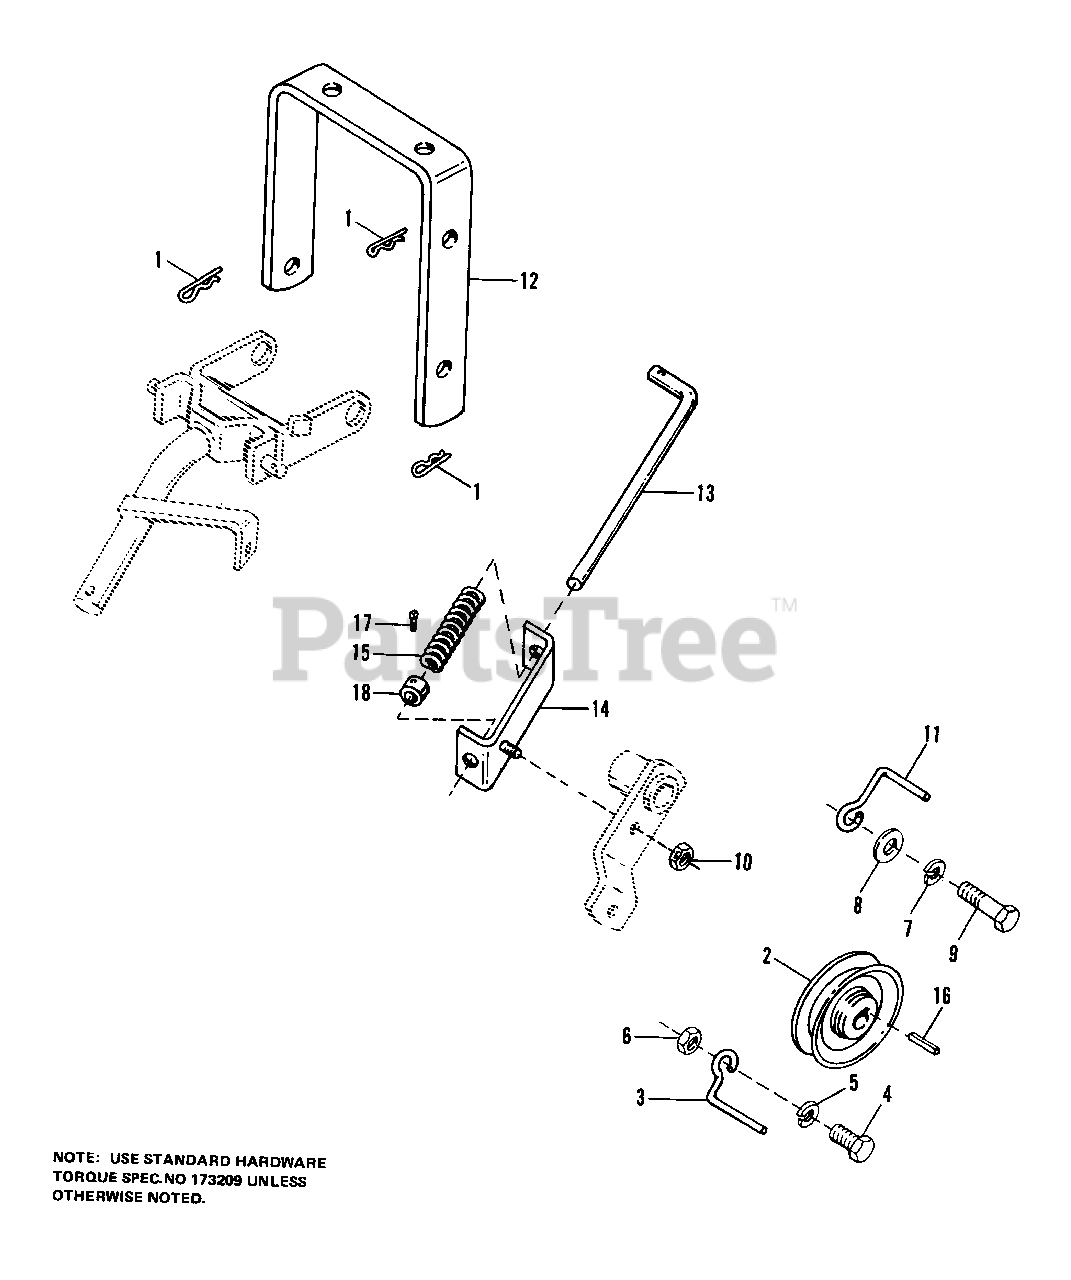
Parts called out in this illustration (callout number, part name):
1	CLIP, Spring
4	CAPSCREW, Hex Hd., 5/16-18 x 1
5	LOCKWASHER, Spring, 5/16
6	NUT, Hex, 5/16-18
7	LOCKWASHER, Spring, 7/16
8	WASHER, Plain, 7/16
9	CAPSCREW, Hex Hd., 7/16-14 x 1-1/4
10	NUT, Hex Lock, 5/16-18
11	STOP, Belt
12	HANDLE, Clutch
13	ROD, Clutch
14	GUIDE ASSY, Rod
17	SETSCREW, Sq. Hd., Cup Pt., 1/4-20 x 3/8
18	COLLAR, Set
